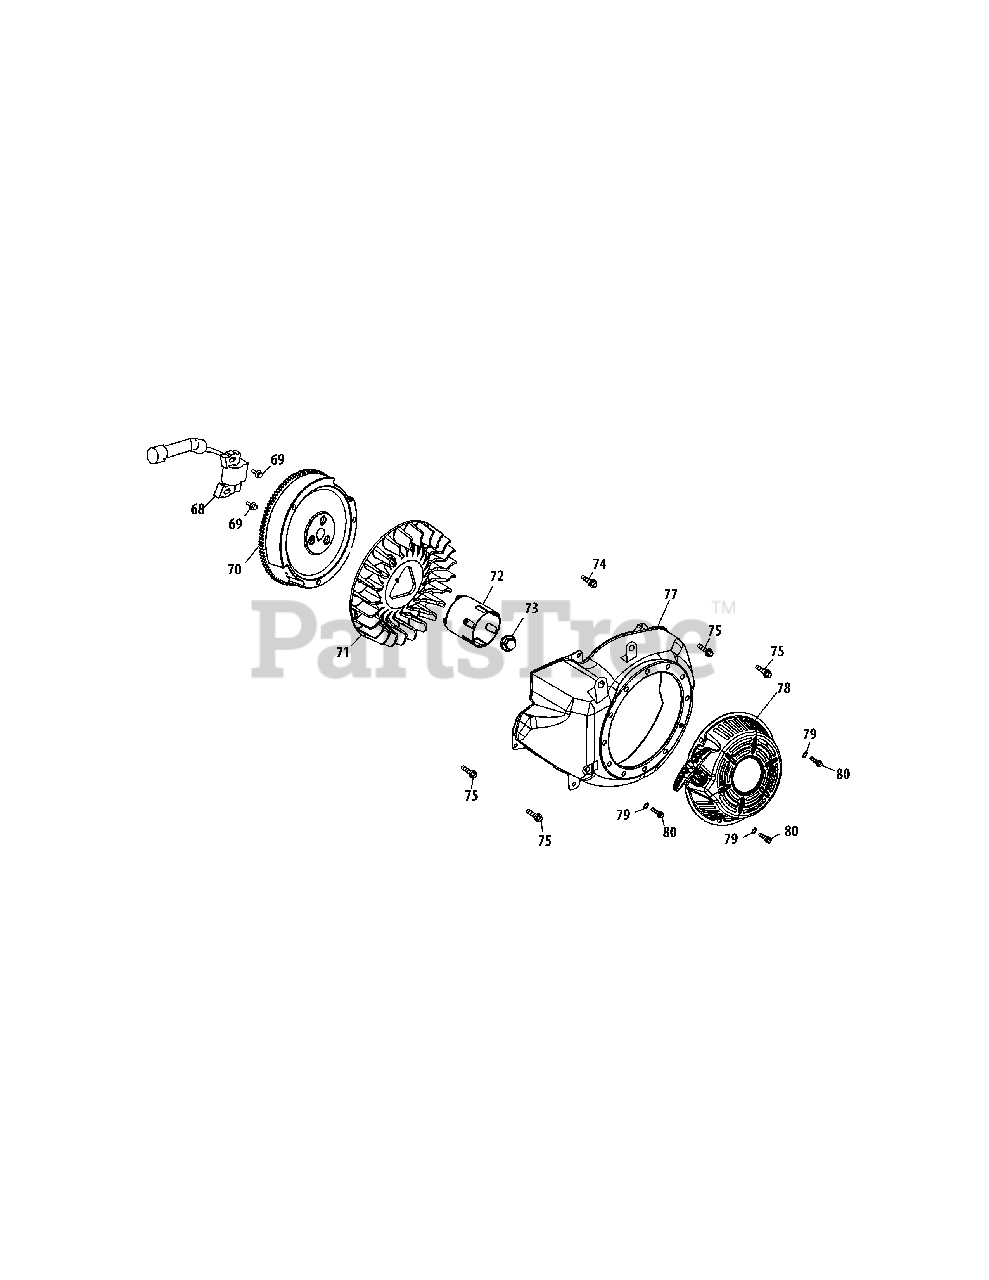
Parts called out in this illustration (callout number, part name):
68	Ignition Coil Assembly
69	Ignition Coil Bolt
71	Fan,Cooling
72	Starter Cup
73	Nut,Special,M16×1.5
74	Bolt M6×16
75	Bolt M6×12
77	Starter Housing
78	Recoil Starter Assy
79	Washer 6
80	Bolt M6×10
